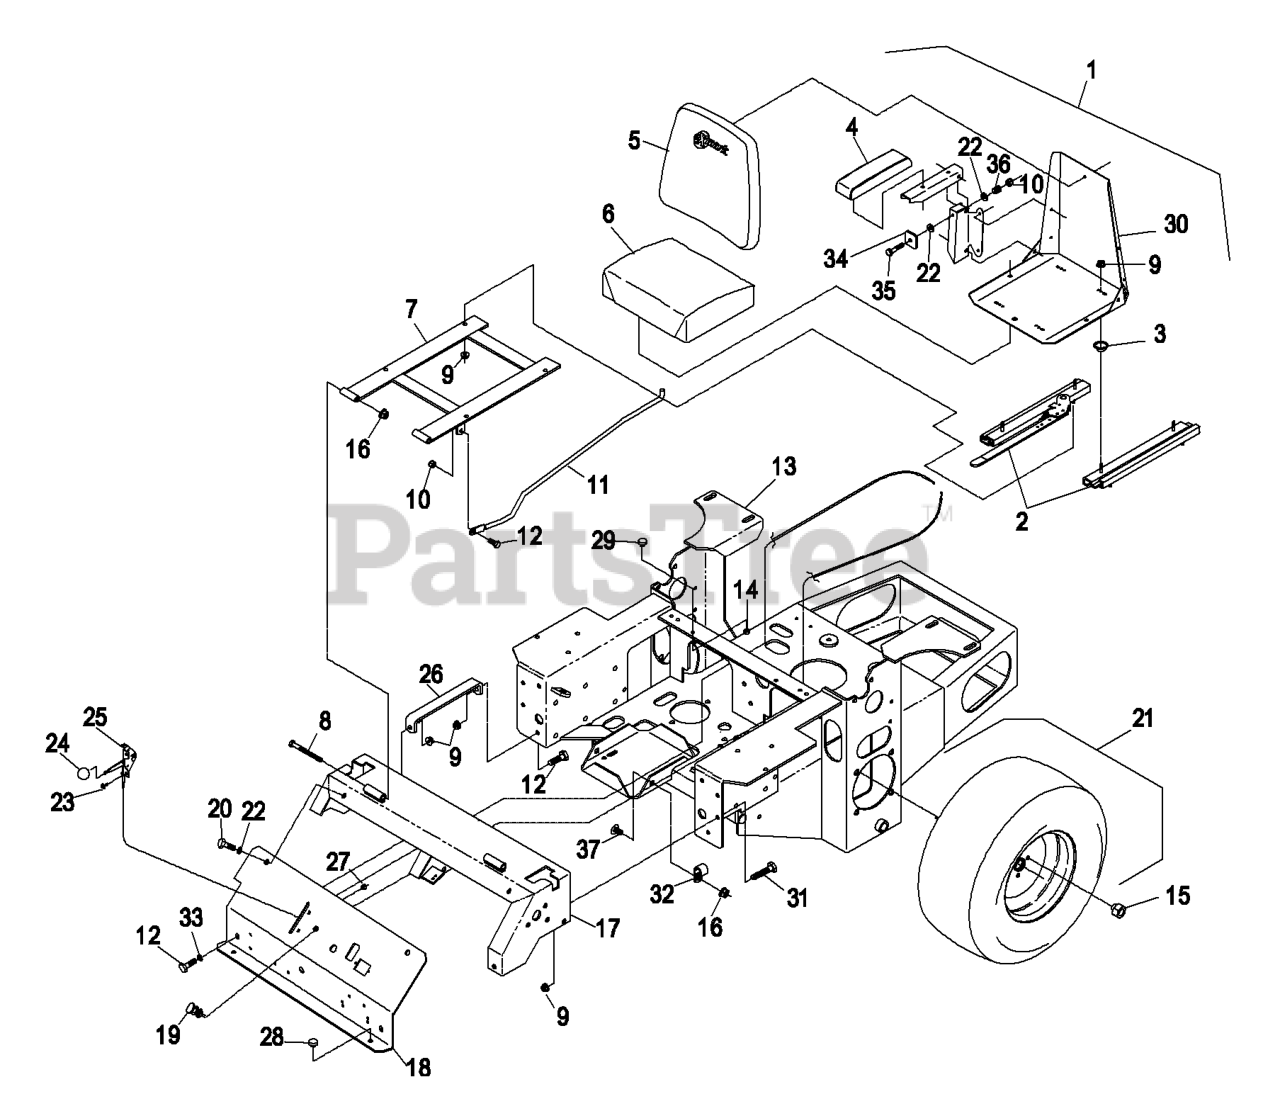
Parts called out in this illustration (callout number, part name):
2	TRACK-SEAT
3	SPACER-TRACK
4	CUSHION,ARMREST RH
8	SCREW-HH
10	NUT-LOCK, NI
11	ROD-RETAINER, SEAT
12	SCREW-HH
14	NUT-LOCK, NI
15	NUT-LUG
16	NUT-LOCK, NI
17	ASM,CONSOLE WELDMENT W/DE
19	CONTROL-CHOKE
20	SCREW-HH
21	ASM,WHEEL AND TIRE
22	WASHER-PLAIN
23	BOLT-CARR
24	KNOB-BALL
25	CONTROL-THROTTLE
27	NUT-LOCK, NI
30	FRAME-SEAT
31	SCREW-HH
32	CLIP-LOOM
33	WASHER-FLAT
34	TAB,ARMREST ADJUSTMENT
35	SCREW-HH
36	SPRING-TANK, FUEL
37	SCREW-CARR
